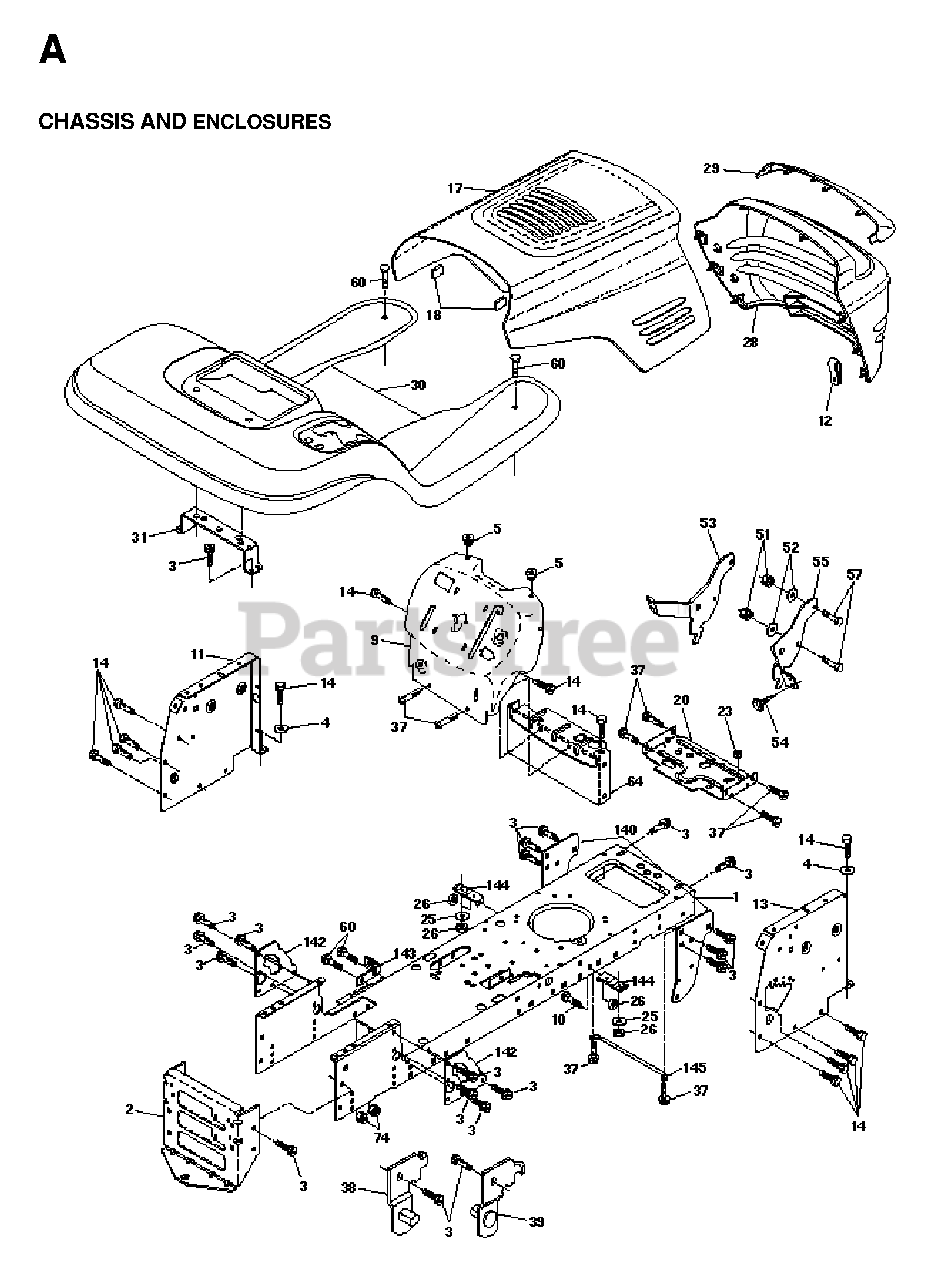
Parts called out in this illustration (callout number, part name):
2	STRETCH DRAWBAR
3	SCREW
5	BUMPER.RUBBER.HOOD
10	BOLT D
11	PANEL DASH LH
13	PANEL DASH RH
18	BUMPER HOOD T
20	PLATE MTG
23	GROMMET T
25	WASHER
26	NUT
38	BRACKET LH PIVOT
39	BRACKET RH PIVOT
51	LOCKNUT
57	BOLT
64	DASH LOWER
74	LOCKNUT
140	BRACKET SUSPENSION FRONT
142	PLATE REINFORCEMENT
143	BRACKET, SWAY BAR
144	BRACKET FOOTREST
145	ROD PIVOT CHASSIS/HOOD
